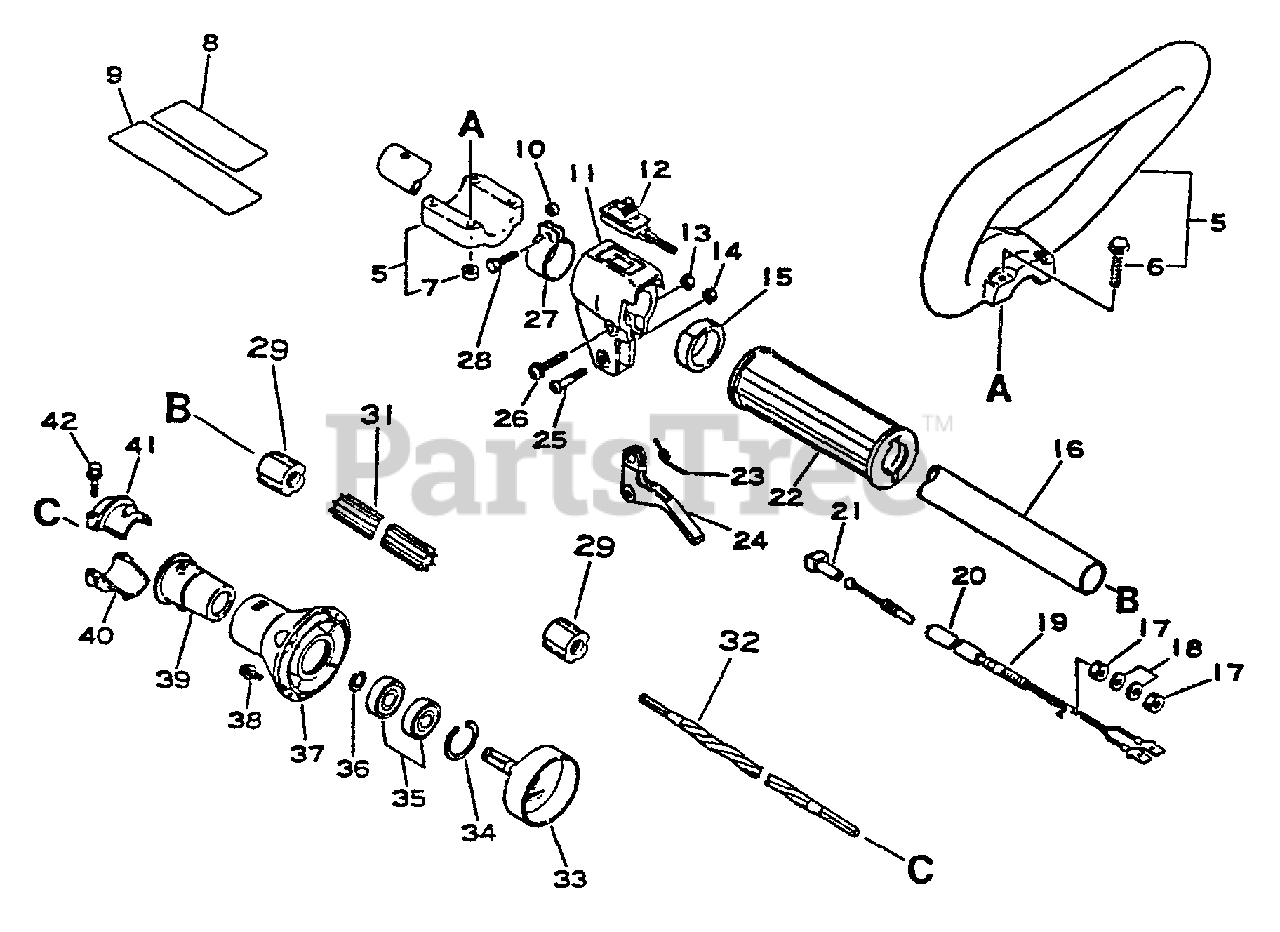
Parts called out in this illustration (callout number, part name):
5	LOOP HANDLE ASSY
6	SCREW 5×35
7	NUT M5
8	LABEL, CAUTION
9	LABEL - CAUTION
10	SPACER, GUARD
11	BRACKET, THROTTLE CONTROL
12	IGNITION SWITCH ASSY
13	NUT M5
14	LOCKNUT - 5
16	MAIN PIPE ASSY 25×1500
18	WASHER 6.5×11.5×0.8
19	CABLE, THROTTLE
21	GUIDE, CABLE
22	GRIP, HANDLE
23	SPRING, THROTTLE
24	TRIGGER, THROTTLE
26	SCREW 5×30
28	BOLT 5×18
31	LINER, FLEXIBLE 21.6×1420
32	DRIVESHAFT - FLEXIBLE L= 1522
33	DRUM, CLUTCH
34	RING, SNAP 28
35	BEARING, BALL 6001
36	RING, RETAINING - 12
37	CASE, CLUTCH - ORANGE
38	SCREW 5×16
41	HOLDER, MAIN PIPE - UPPER
42	BOLT - 5×25
